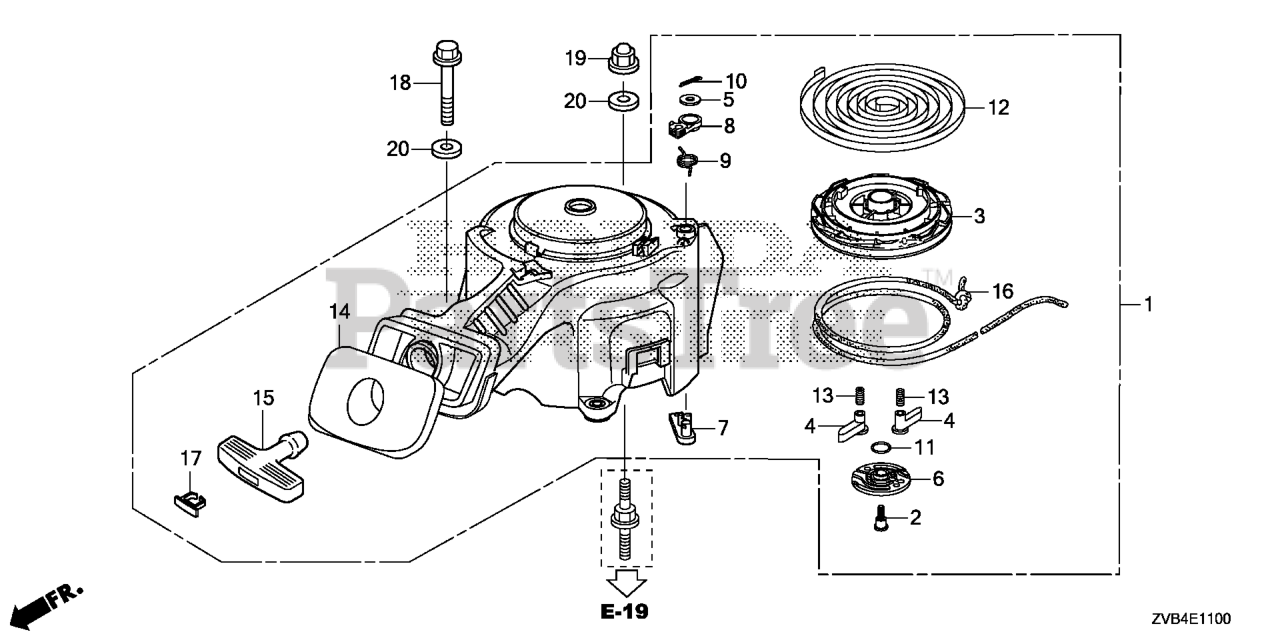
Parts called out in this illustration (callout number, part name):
1	STARTER ASSY., RECOIL
2	SCREW, TAPPING (5X20)
3	REEL, RECOIL STARTER
4	RATCHET, STARTER
6	GUIDE, RATCHET
7	STOPPER, REEL
8	ARM, STOPPER
9	SPRING, STOPPER
10	PIN, SPLIT
11	SPRING, FRICTION (ENGINE NO.)
12	SPRING, RECOIL STARTER
13	SPRING, RETURN (ENGINE NO.)
14	SEAL, RECOIL
15	GRIP, STARTER
16	ROPE, RECOIL STARTER
17	CAP, STARTER KNOB
18	BOLT, FLANGE (6X40)
19	NUT, FLANGE CAP (6MM)
20	WASHER, PLAIN (6MM)
